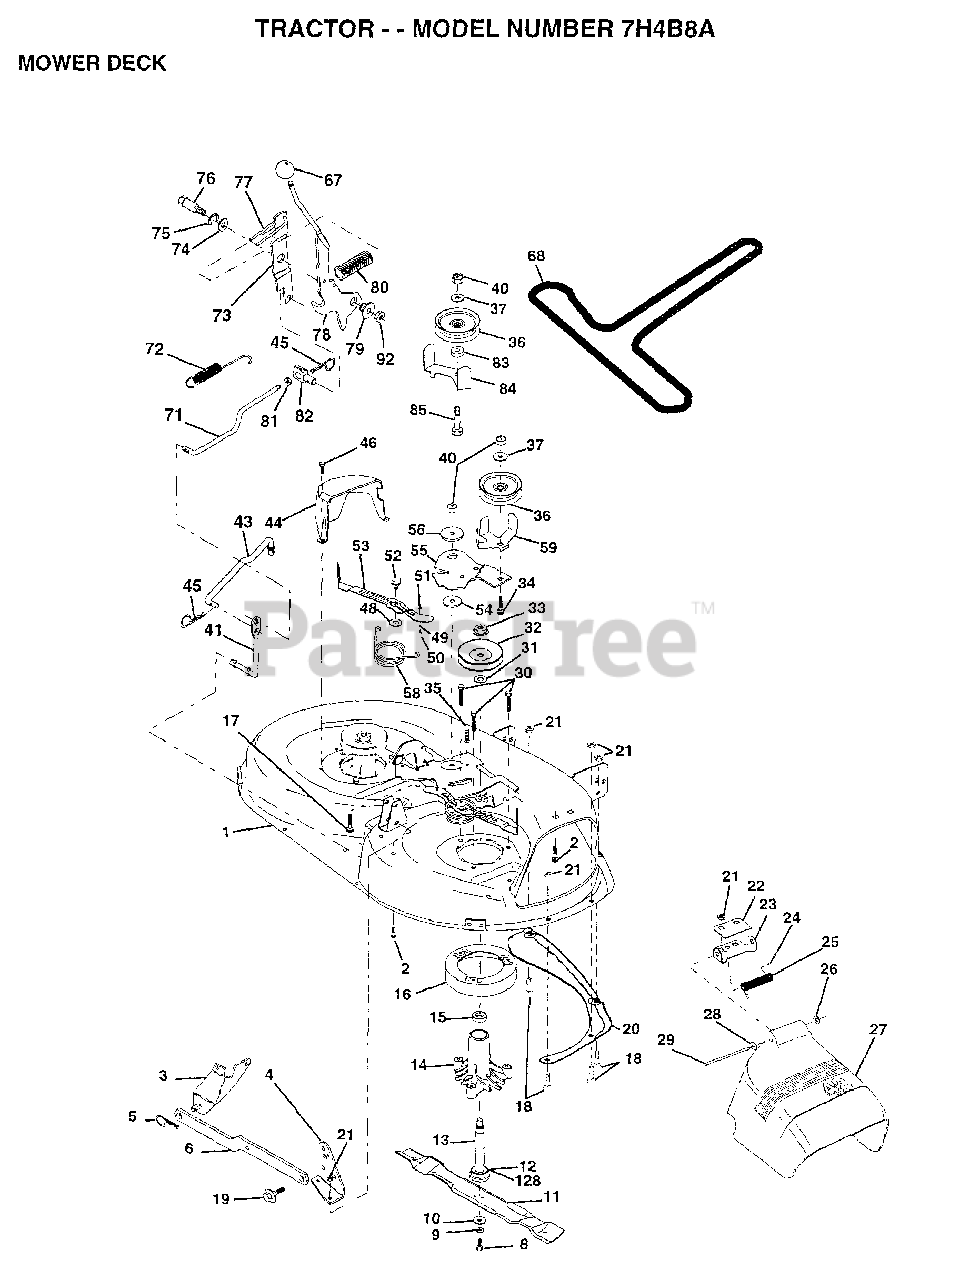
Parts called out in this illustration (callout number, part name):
1	DECK.WELD.42.
2	BOLT
3	BRKT ASM SWAY BAR
4	BRKT DECK SW BAR
8	BLADE BOLT
10	WASHER.HARD.BLADE
11	"BLADE.42"" HIPERF"
12	BEARING.BALL
14	HSG ASM MANDREL
15	BEARING
16	STRIPPER RND MWR
17	BOLT RDHD 3/8-16
18	BOLT
19	BOLT SHD 5/16-18
22	STIFFENER BRKT
23	DEFLECTOR BRKT
24	CAP-SLEEVE LT
25	SPRING TORSION
26	NUT PUSH M
27	DEFLECTOR.SHIELD
28	WASHER
29	HINGE ROD
31	WASHER
32	PULLEY.MANDREL.42
34	BOLT
35	XMAS TREE FASTNER
36	FLAT IDLER PULLEY
37	WASHER
41	PIVOT ROD
43	ROD CLUTCH W/NIBS
44	GUARD MAND LH BLK
45	RETAINER M
46	SCREW.1/4-20X5/8
48	HARD SMALL WASHER
50	SHOULDER BOLT
51	LOCKNUT
52	BOLT.SHLD.5/16-18
53	BRAKE PAD ARM ASM
54	HARDENED WASHER
56	SPACER RETAINER
58	SPRING TORSN BRAK
59	GUARD IDLER TUV
67	KNOB T(3/8 HOLE)
68	BELT.V.T-PATH
71	ROD CLUTCH 38/42
72	RETURN SPRING
73	CLUTCH ARM SECOND
74	WASHER
75	RING
76	SHOULDER BOLT
77	SPRING KEEPER
79	BUSHING
80	SPRING.CLUTCH.MWR
81	NUT
82	TRUNION ADJ
83	WASHER
85	BOLT RDHD 3/8-16
92	NUT
128	WASHER.FELT.
